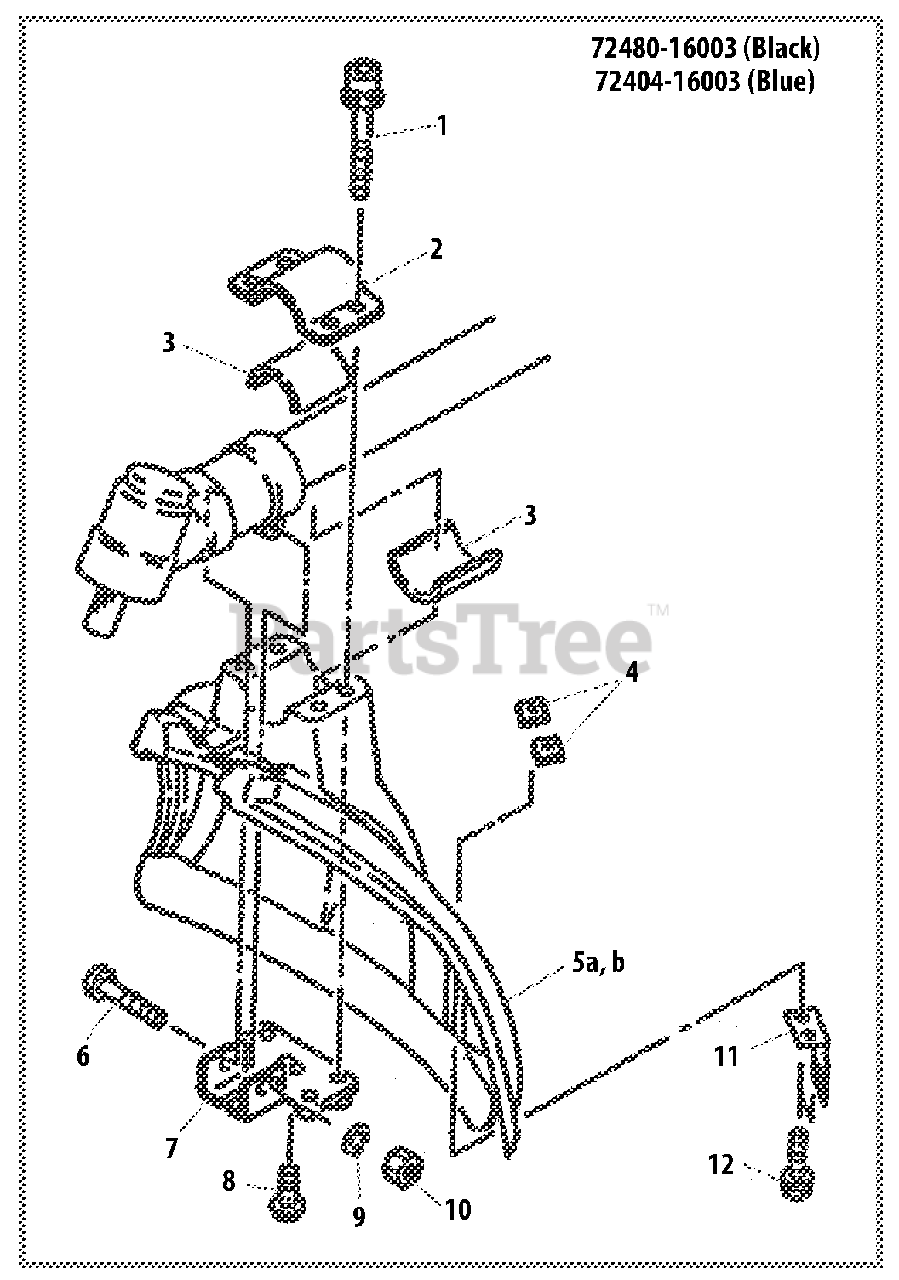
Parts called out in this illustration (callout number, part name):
1	BOLT M5×45
2	CLAMP, UPPER
3	SPACER
4	NUT M5
5	SHIELD, DEBRIS
5	SHIELD, DEBRIS - BLUE
6	BOLT M5×35
7	PLATE, SHIELD MOUNTING
8	SCREW HILO 4×10
9	WASHER 5 MM
10	NUT M5
11	CUTTER
12	BOLT M5×16
72404-16003	DEBRIS SHIELD KIT - BLUE
72480-16003	DEBRIS SHIELD ASSY
